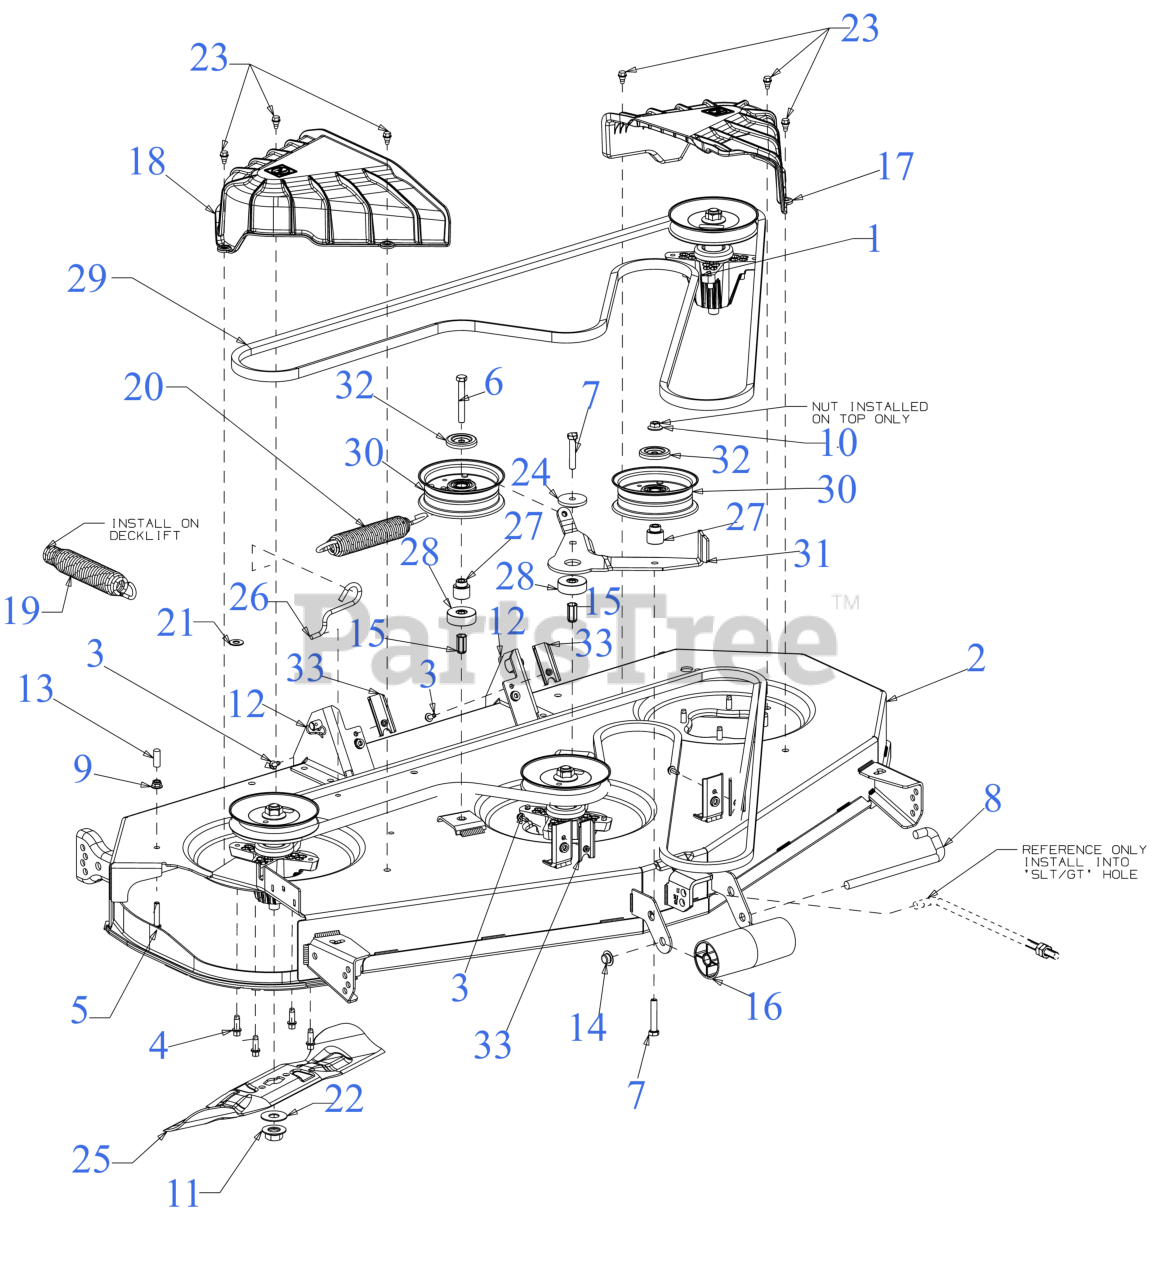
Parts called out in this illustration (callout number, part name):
1	SPINDLE ASSEMBLY
2	54" FAB FLAT TOP DECK SHELL
3	SCREW M6-1 x .625
4	SCREW 5/16-18 x .875
5	SCREW 5/16-18 x 1.5 LG
6	SCREW 3/8-16 x 2.75 GR5
7	SCREW 3/8-16 x 2.0 GR 8
8	ROLLER PIN 1/2 x 7.31
9	FLANGE LOCK NUT 5/16-18
10	FLANGE LOCK NUT
11	HEX FLANGE NUT 5/8-18 GR5
12	BOW TIE COTTER PIN
15	NUT RIVET 3/8-16
17	SPINDLE COVER (LH)
18	SPINDLE COVER (RH)
19	LIFT ASSIST SPRING (LARGE)
20	SPRING 1.25" DIA x 8.5" LONG
21	FLAT WASHER .401X.88
22	FLAT WASHER .635X1.585X.062 HDN
23	SHOULDER SCREW 1/4-20 x .50
24	SHOULDER SPACER
25	18.611" BLADE (2IN1) (S SHAPE CENTER HOLE)
25	Cub Cadet 54" HI LIFT BLADE SET (S SHAPE CENTER HOLE) (-05086)
25	Troy-Bilt 54" HI LIFT BLADE SET (S SHAPE CENTER HOLE)
25	18.611" XTREME BLADE (2IN1) (S SHAPE CENTER HOLE)
25	Cub Cadet 54" XTREME BLADE SET (S SHAPE CENTER HOLE) (-05086-X)
25	Troy-Bilt 54" XTREME BLADE SET (S SHAPE CENTER HOLE)
25	18.611" LOW LIFT (S SHAPE CENTER HOLE)
25	Cub Cadet 54" LOW LIFT BLADE SET (S SHAPE CENTER HOLE) (-05086-L)
25	Troy-Bilt 54" LOW LIFT BLADE SET (S SHAPE CENTER HOLE)
26	DECK SPRING HOOK
27	SHOULDER SPACER
28	SPACER .385ID x 1.75OD x .585THK
29	V-BELT B SEC x 139
29	Cub Cadet 54" DECK DRIVE BELT
29	Genuine Factory Parts 54" DECK BELT
30	IDLER PULLEY 4.50" DIA
31	IDLER PIVOT BRACKET
32	IDLER PULLEY CAP
